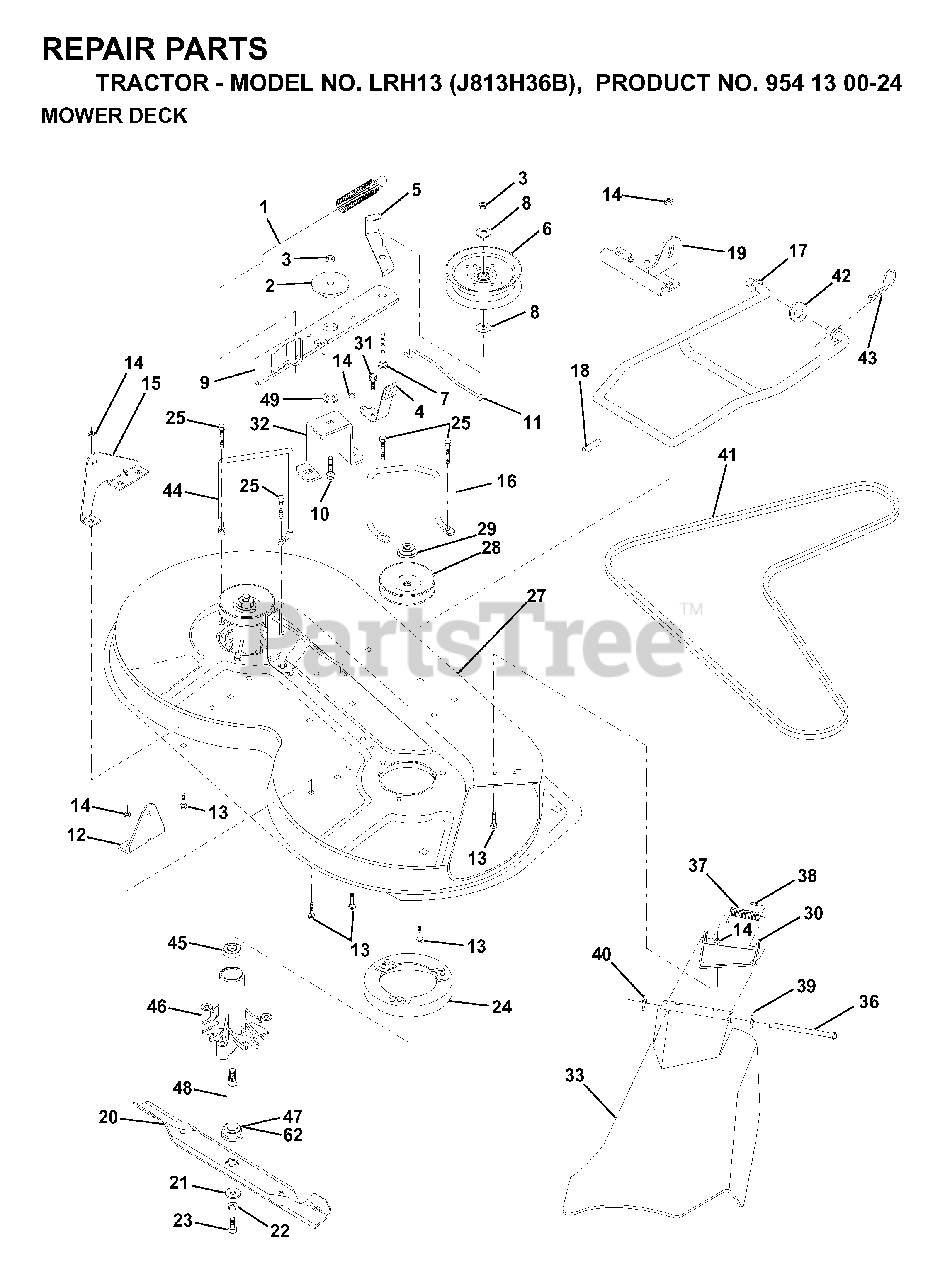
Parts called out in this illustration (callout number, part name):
1	SPRING-MOWER CLUTCH
2	SPACER RETAINER
3	LOCKNUT
4	BRAKE ASSEMBLY
5	IDLER BELT GUIDE
6	PULLEY IDLER
7	BOLT
8	WASHER
9	IDLER ARM ASSY
10	BOLT.3/8-14X1.25
11	BRAKE ROD
12	BRKT LIFT REAR
13	BOLT
14	LOCKNUT
15	BRKT LIFT REAR LH
16	BELT KEEPER
17	MOWER LINK STABILIZER
18	PIN GROOVE
19	BRKT LINK STABILIIZER
21	WASHER.BLADE
22	LOCKWASHER
23	BLADE BOLT
24	STRIPPER
25	SCREW THDROL ROLLING WASHER HD
27	MOWER HOUSING
28	PULLEY, MANDREL
29	NUT
30	BRACKET ASM DEFLECTOR
32	SUPT,IDLER ARM
33	DEFLECTOR
36	HINGE ROD
37	SPRING TORSION
38	CAP-SLEEVE LT
39	WASHER
40	NUT PUSH M
42	WASHER
43	SPRING RETAINER
44	KEEPER LH
46	HSG MANDREL
47	BEARING
48	SHAFT ASM VENT
49	HARDENED WASHER
62	WASHER FELT
